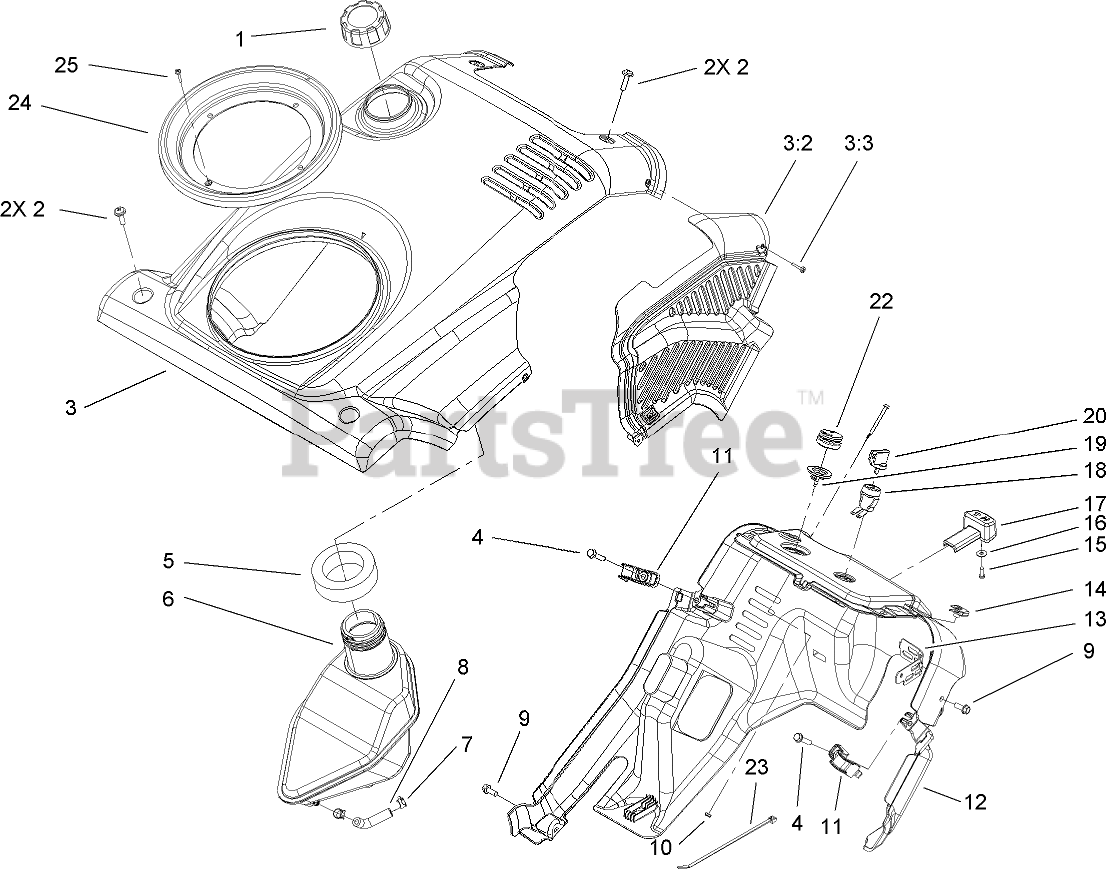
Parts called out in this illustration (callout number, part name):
1	4-CYCLE GAS CAP ASM
2	SCREW-PPH
3	SHROUD ASM
3:2	BAFFLE-HEAT, 4-CYCLE
3:3	SCREW-PPH
4	SCREW-PLASTITE
5	SEAL-TANK
6	TANK-GAS
7	CLAMP-HOSE
8	HOSE-FUEL
9	SCREW-HWH
10	NUT-HEX
11	CLIP-SHROUD
12	SHROUD-LOWER
13	GUARD-EXHAUST
15	SCREW-PPH
16	WASHER-PLAIN
17	KNOB-CHOKE
18	SWITCH
19	BODY-PRIMER
20	KEY-IGNITION
22	BULB-PRIMER
23	TIE-CABLE
24	SEAL-RING, CHUTE
25	SCREW-PPH
